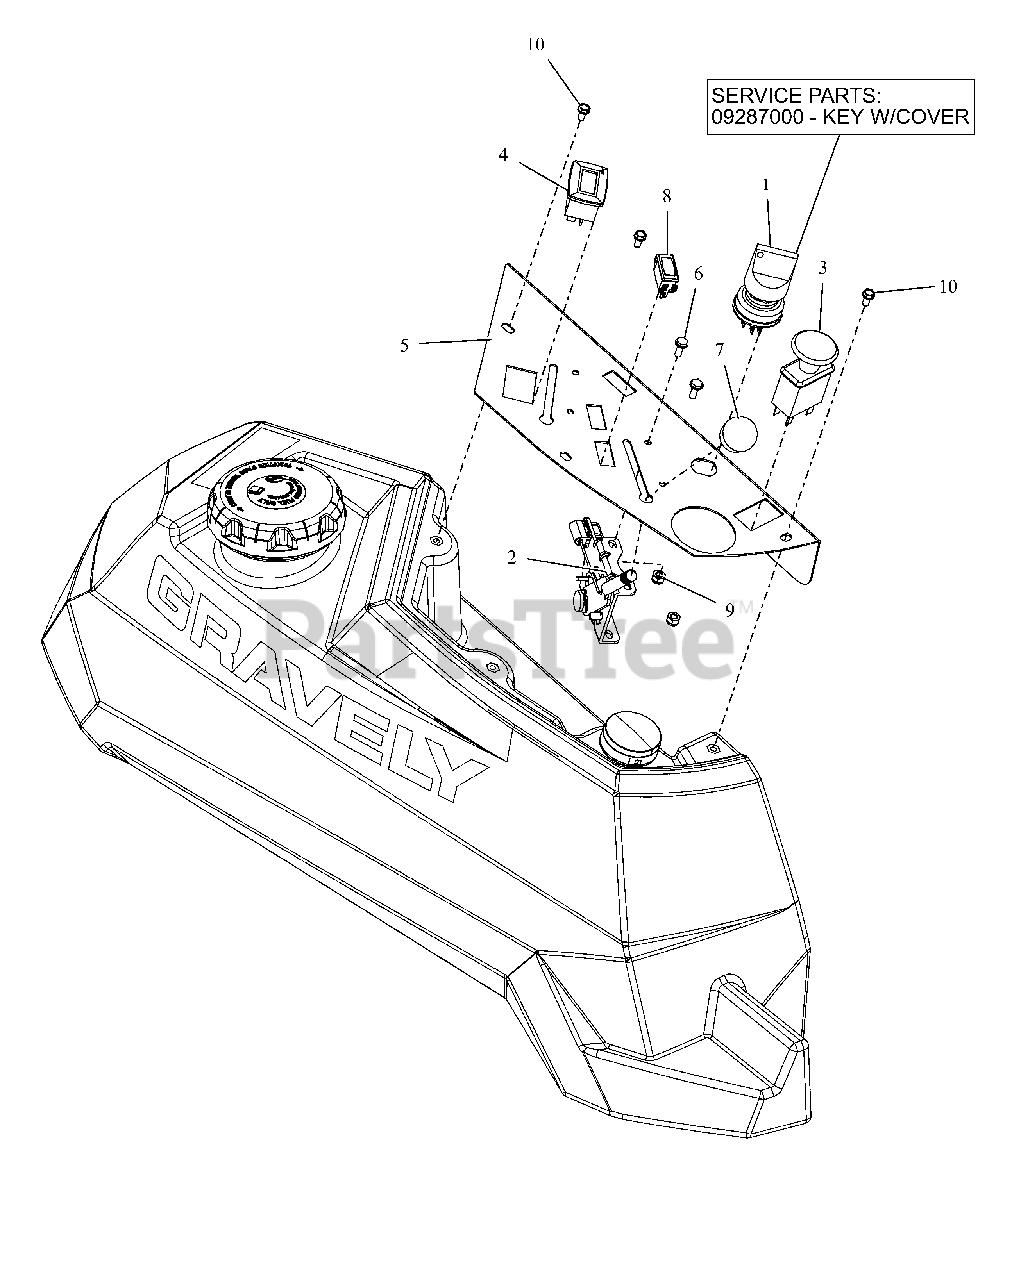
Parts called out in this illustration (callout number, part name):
1	SWITCH, IGNITION
1	KEY, W/ SHIELD
2	CABLE, PRO-CTRL 35.50"
3	SWITCH, CLUTCH
4	METER, HOUR W/MAINTENANCE
5	PT100 CONTROL PANEL - RED
6	@SCR-MCH 10-24X.50 HWH YWZC
7	KNOB-CONTROL-BLACK .38-16X.50
8	LIGHT,INDICATOR
9	@NUT-LK-NYL 10-24 W/INSRT YWZC
10	SCR-MCH 10-24X.38 HWHSTAINLESS
